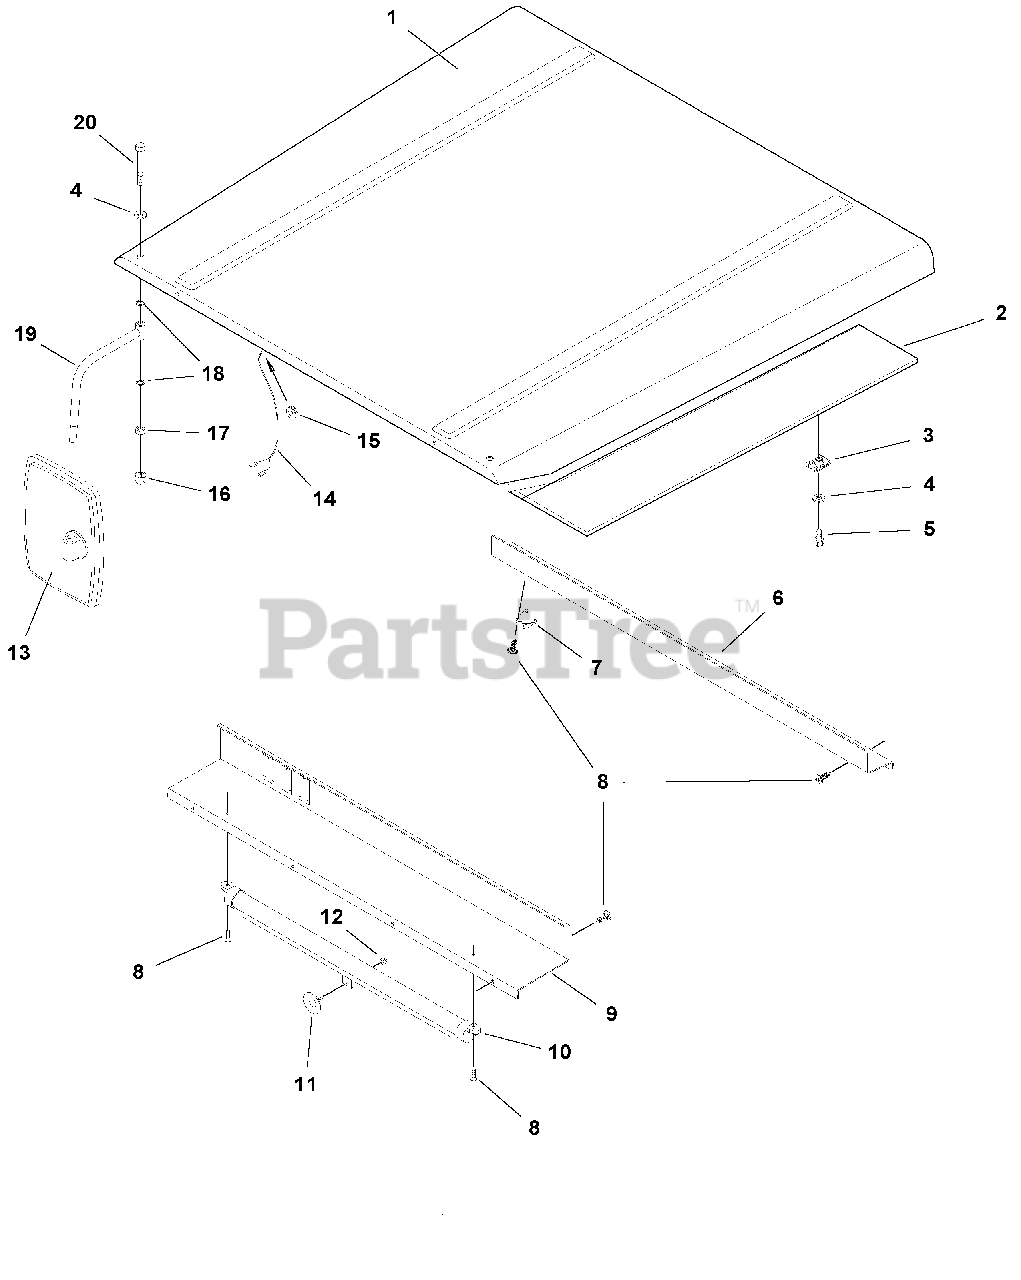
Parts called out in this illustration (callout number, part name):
2	INNER ROOF DECOR
3	NUT, M8 13965
6	FRAME COVER, Rear
7	COAT HANGER
8	SCREW, Self-Tapping Phillips Hd., 4.8 x 16
9	FRAME COVER, Front
10	SHIELD, Sunlight
11	VAC SOCKET, with Screw
12	NUT, Cap M4
14	WIRING ASSEMBLY, Headlight
15	CABLE GUIDE, 12MM
